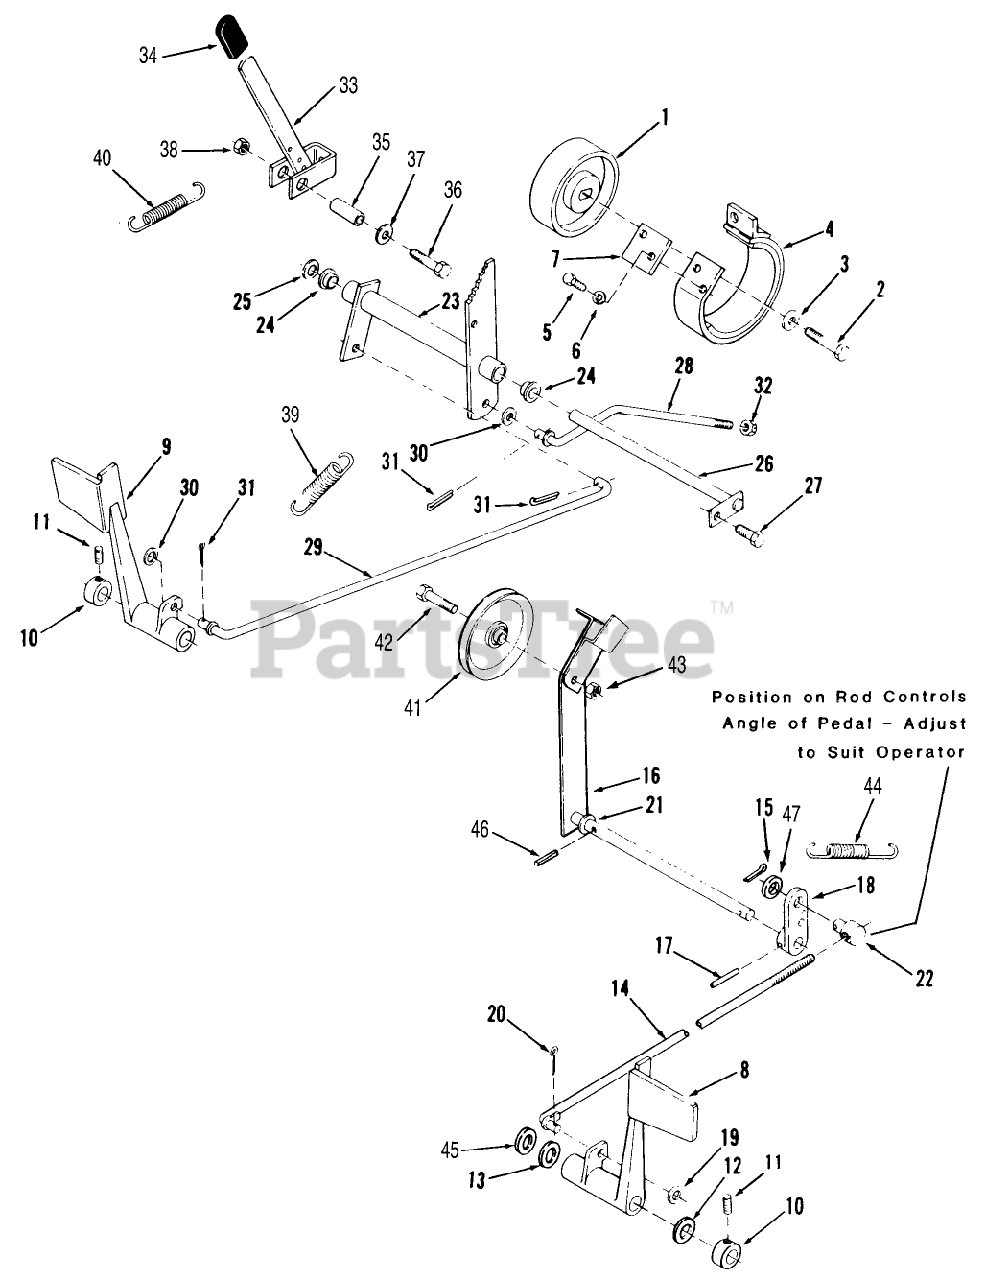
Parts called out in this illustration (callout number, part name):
1	DRUM-BRAKE
2	SCREW-HEX HD CAP
3	WASHER
4	BRAKE BAND ASM
10	COLLAR
12	WASHER-BOWED
13	WASHER
14	ROD AND GUIDE ASM
17	PIN-SPIROL
19	WASHER-NYLON
21	SHIM-WASHER
22	TRUNNION
24	BUSHING-FLANGED
26	ROD ASM
27	SCREW
28	ROD-REAR BRAKE
30	WASHER-NYLON
34	GRIP
35	SPACER
39	SPRING-BRAKE
40	SPRING-EXTENSION
42	BOLT-SPECIAL HEX
44	SPRING-CLUTCH
46	PIN-SPIROL
